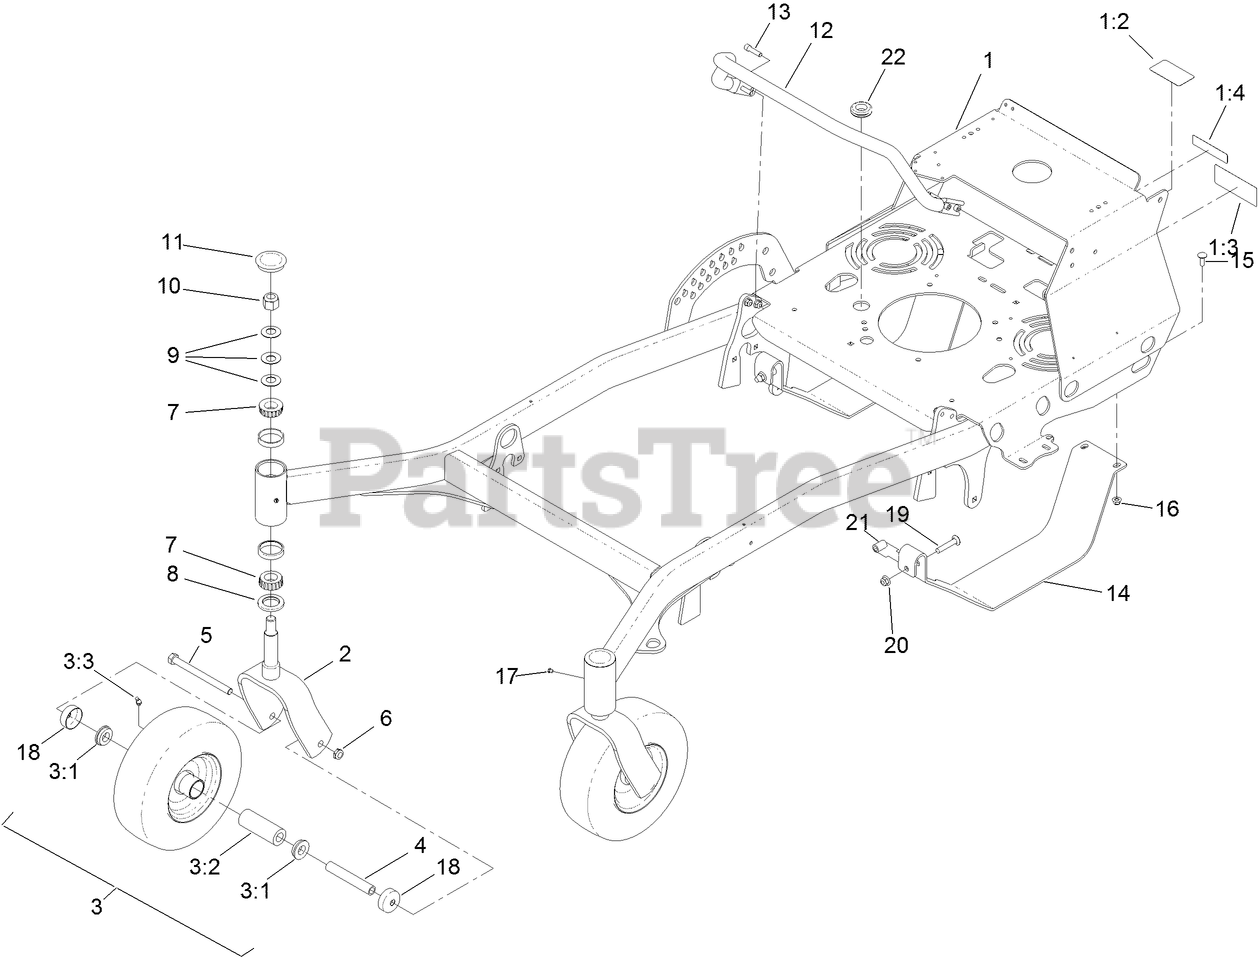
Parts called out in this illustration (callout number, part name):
1	FRAME ASM
1:2	DECAL - BYPASS
1:3	DECAL-WARNING, SULKY
1:4	DECAL-WARNING
2	FORK-CASTER
3	WHEEL AND TIRE ASM
3:1	BUSHING
3:2	BEARING
3:3	FITTING-GREASE
4	SPACER
5	SCREW-HH
6	NUT-HEX
7	BEARING-ROLLER, TAPERED
8	SEAL-GREASE
9	WASHER-BELLVILLE
10	NUT-LOCK, NI
11	CAP-GREASE
12	TUBE, MUFFLER GUARD
13	SCREW-HSH
14	GUARD-TRANSMISSION
15	BOLT-CARR
16	NUT-HF, NI
18	GUARD-SEAL
19	BOLT-CARRIAGE
20	NUT-HF, NI
21	SPACER
22	GROMMET
